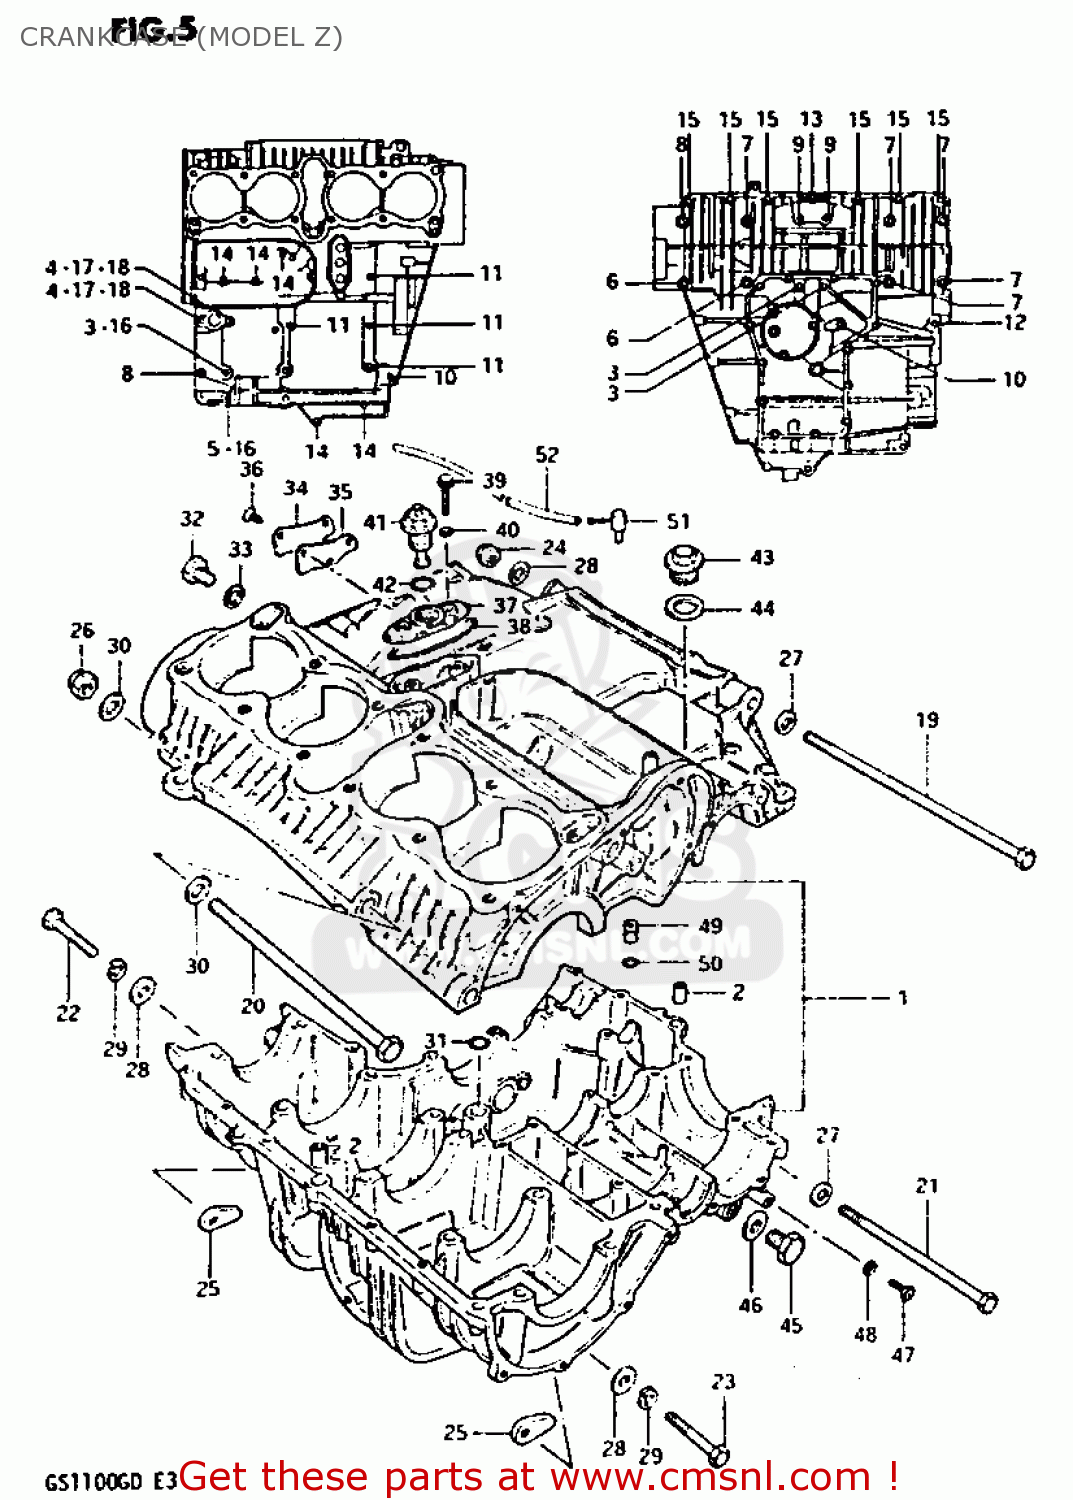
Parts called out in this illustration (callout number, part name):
1	CRANKCASE SET
2	PIN
3	BOLT(8X125)
4	BOLT
5	BOLT(8X105)
6	BOLT(8X100)
7	BOLT 8X90
8	BOLT 8X65
9	BOLT
10	BOLT (6X90)
11	BOLT (6X75)
12	BOLT
13	BOLT ,6X50
14	BOLT,UNDER
15	BOLT 6X35
16	NUT
17	NUT
18	GASKET 8.2X14X1 (NAS)
19	BOLT 10X270
20	SHAFT,REAR SWING ARM
21	BOLT(10X165)
22	BOLT 10X60
23	BOLT (10X50)
24	NUT
25	NUT
26	NUT 12MM
27	WASHER(10.5X20X3.2)
28	WASHER
29	WASHER,LOCK,10
30	WASHER
31	O RING(D:3.2,ID:12.9)
32	PLUG(14X12)
33	GASKET(14X19.2X2) (NAS)
34	CAP,OIL GALLERY
35	GASKET,OIL GALLERY CAP (NAS)
36	SCREW
37	HOUSING,OIL PRESSURE SWITCH
38	O RING,PRESSURE SWITCH HOUSING
39	BOLT 6X25
40	GASKET(5.8X13X1.2) (NAS)
41	SWITCH ASSEMBLY
42	O RING(D:1.9,ID:18.8)
43	PLUG
44	GASKET
45	PLUG
46	GASKET(14X19.2X2) (NAS)
47	SCREW(6X10)
48	GASKET(5.8X13X1.2) (NAS)
49	UNION
50	O RING(D:1.05,ID:3.1)
51	BPLUG,BEVEL GEAR BREATHER
52	HOSE
